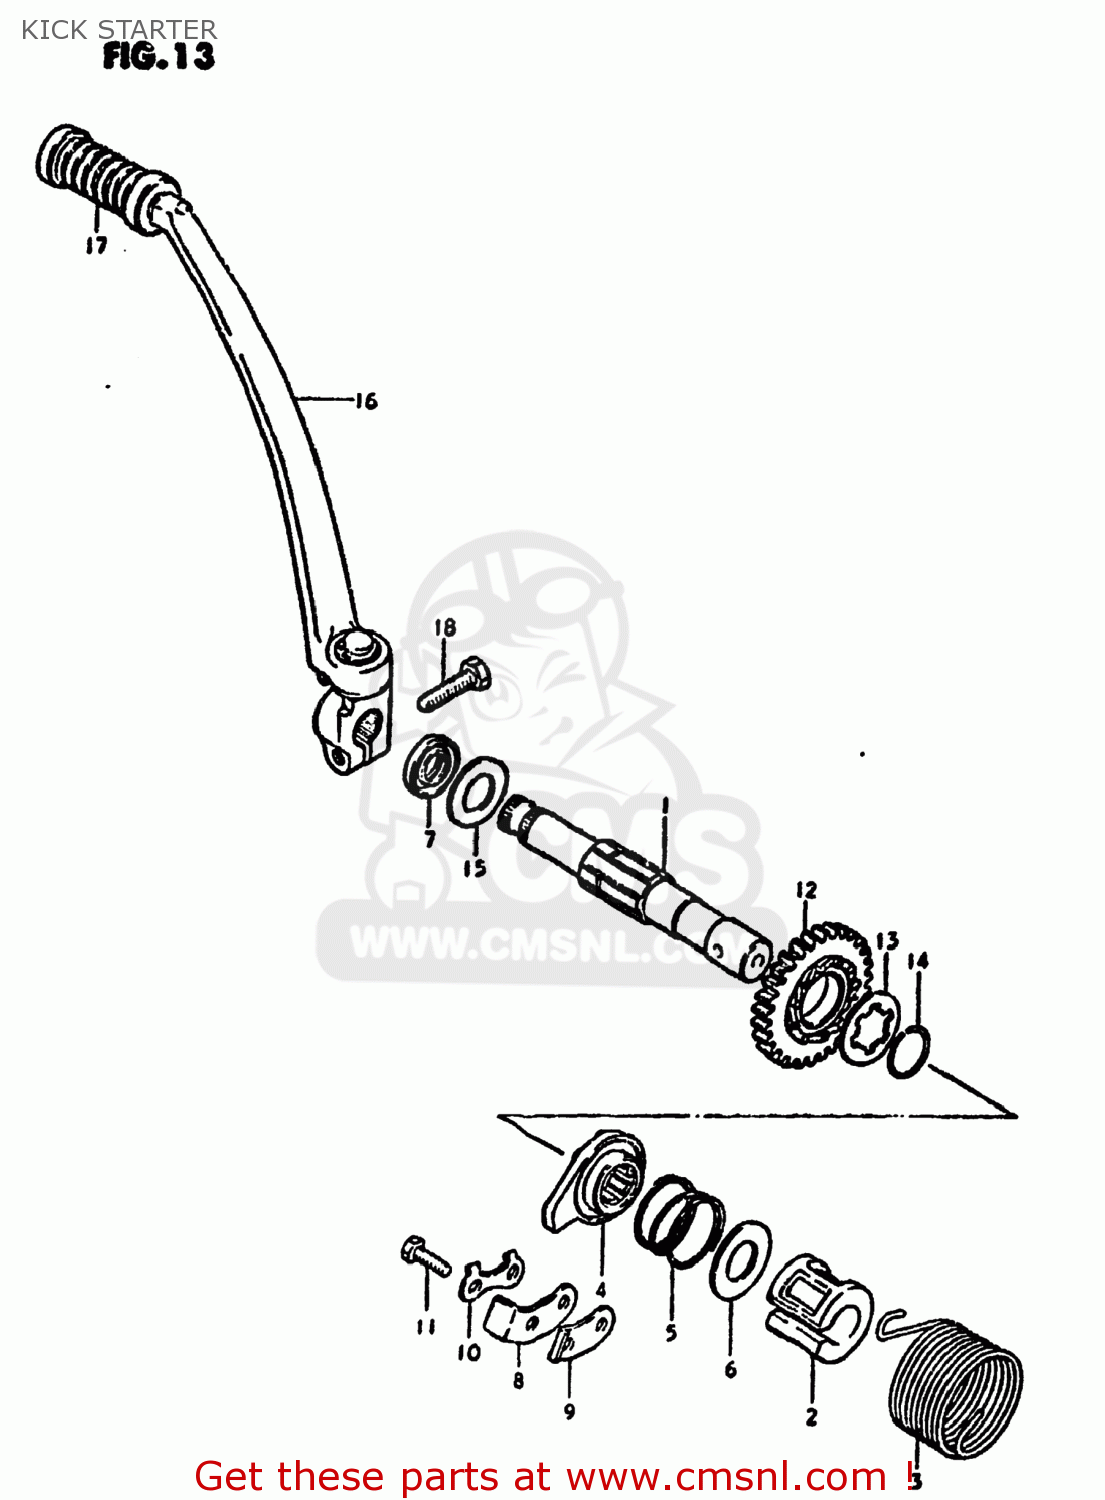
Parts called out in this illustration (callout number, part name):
1	SHAFT,KICK STARTER
2	GUIDE,KICK STARTER SFT SPRING
3	SPRING
4	STARTER,KICK
5	SPRING
6	WASHER
7	SEAL,OIL(16X30X8)
8	GUIDE,KICK STARTER
9	STOPPER,KICK STARTER
10	WASHER
11	BOLT, UPPER
12	GEAR,KICK STARTER DRIVE
13	WASHER,LOCK
14	CIRCLIP
15	WASHER(16X30X1)
16	LEVER ASSEMBLY,KICK STARTER
17	RUBBER,KICK STARTER PEDAL
18	BOLT
